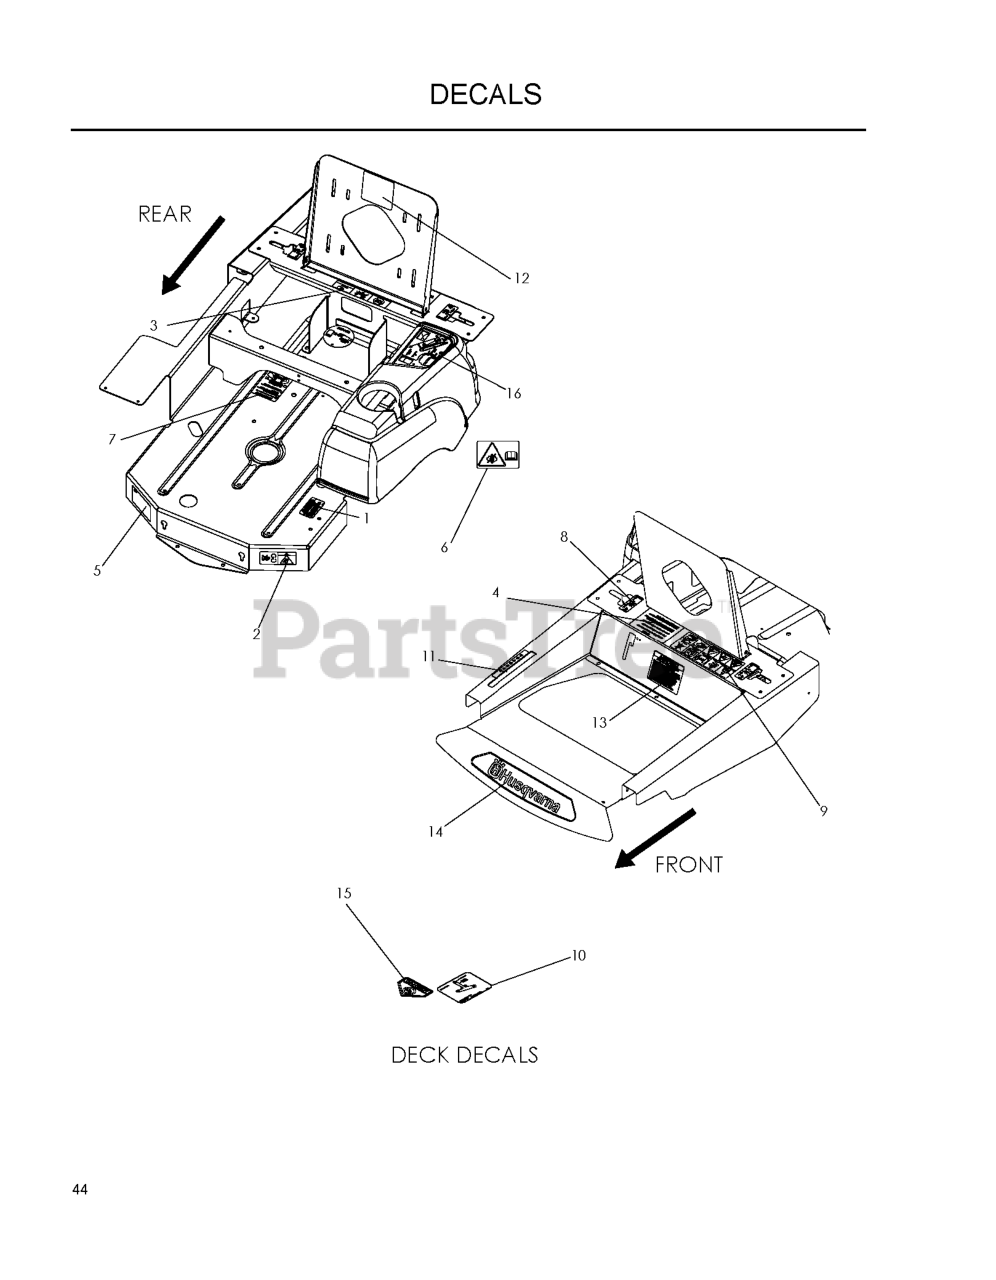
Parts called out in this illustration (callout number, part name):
1	DECAL, PROP. 65
2	DECAL, BELT DRIVE
3	EURO DECAL-BATTERY WARNIN6
4	DECAL, START
5	DECAL, DO NOT TOW
6	DECAL, EXITING MOWER
7	DECAL, SERVICE
8	DECAL, MOTION CONTROL
9	DECAL, SAFETY WARNING
10	DECAL, BELT
11	DECAL, HEIGHT
12	DECAL, CUSTOMER RESPNSIBILITY
13	DECAL, WARNING
14	DECAL, HUSQ 12" BLUE
15	DECAL, CPSC
16	DECAL, IGNITION CONSOLE
